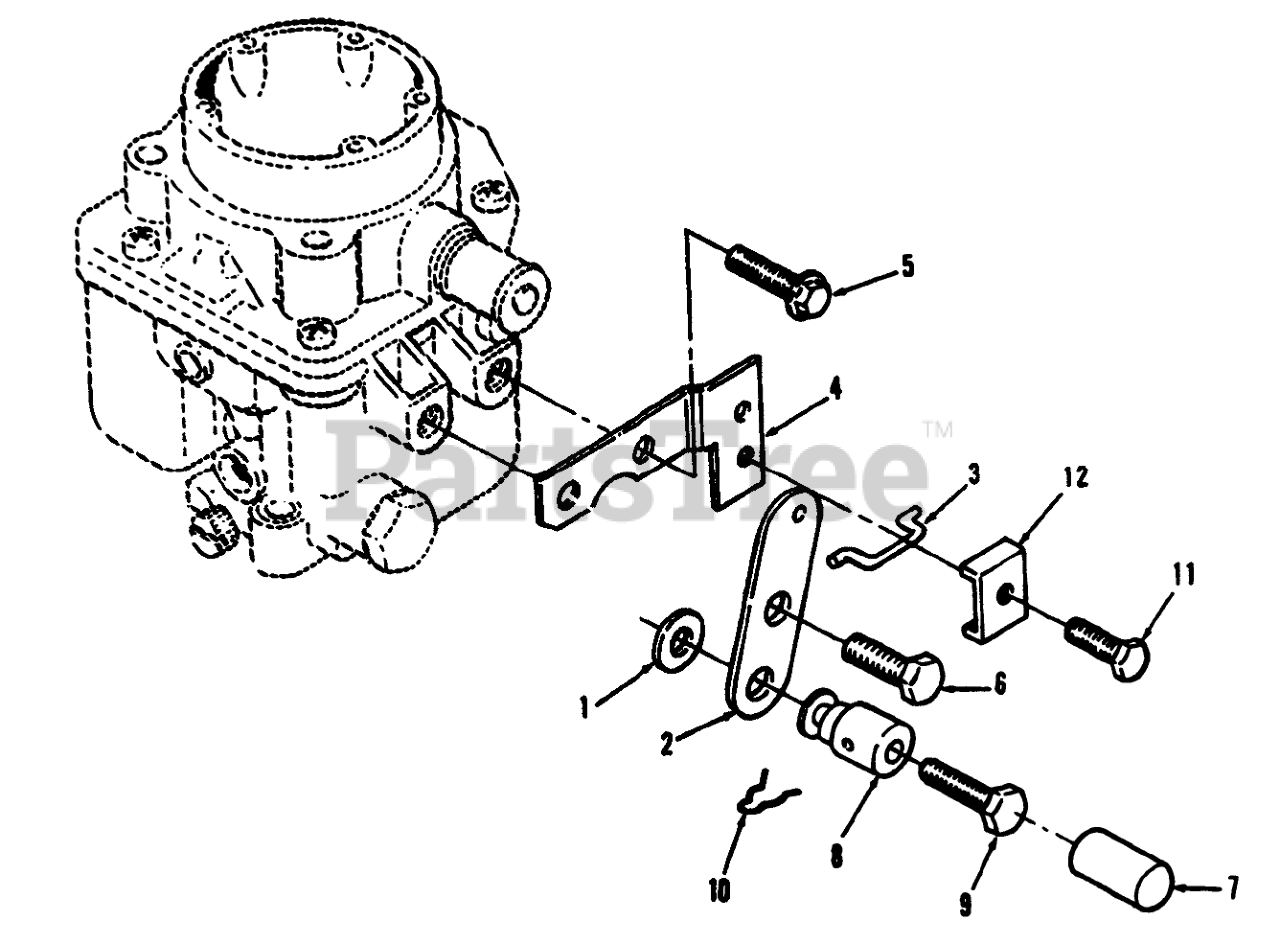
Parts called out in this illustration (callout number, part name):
1	Washer
2	Lever
3	Link
4	Plate
5	Bolt
6	MACHINE SCREW
8	Swivel
9	Bolt
10	PIN-COTTER
11	SCREW-TAPPING
